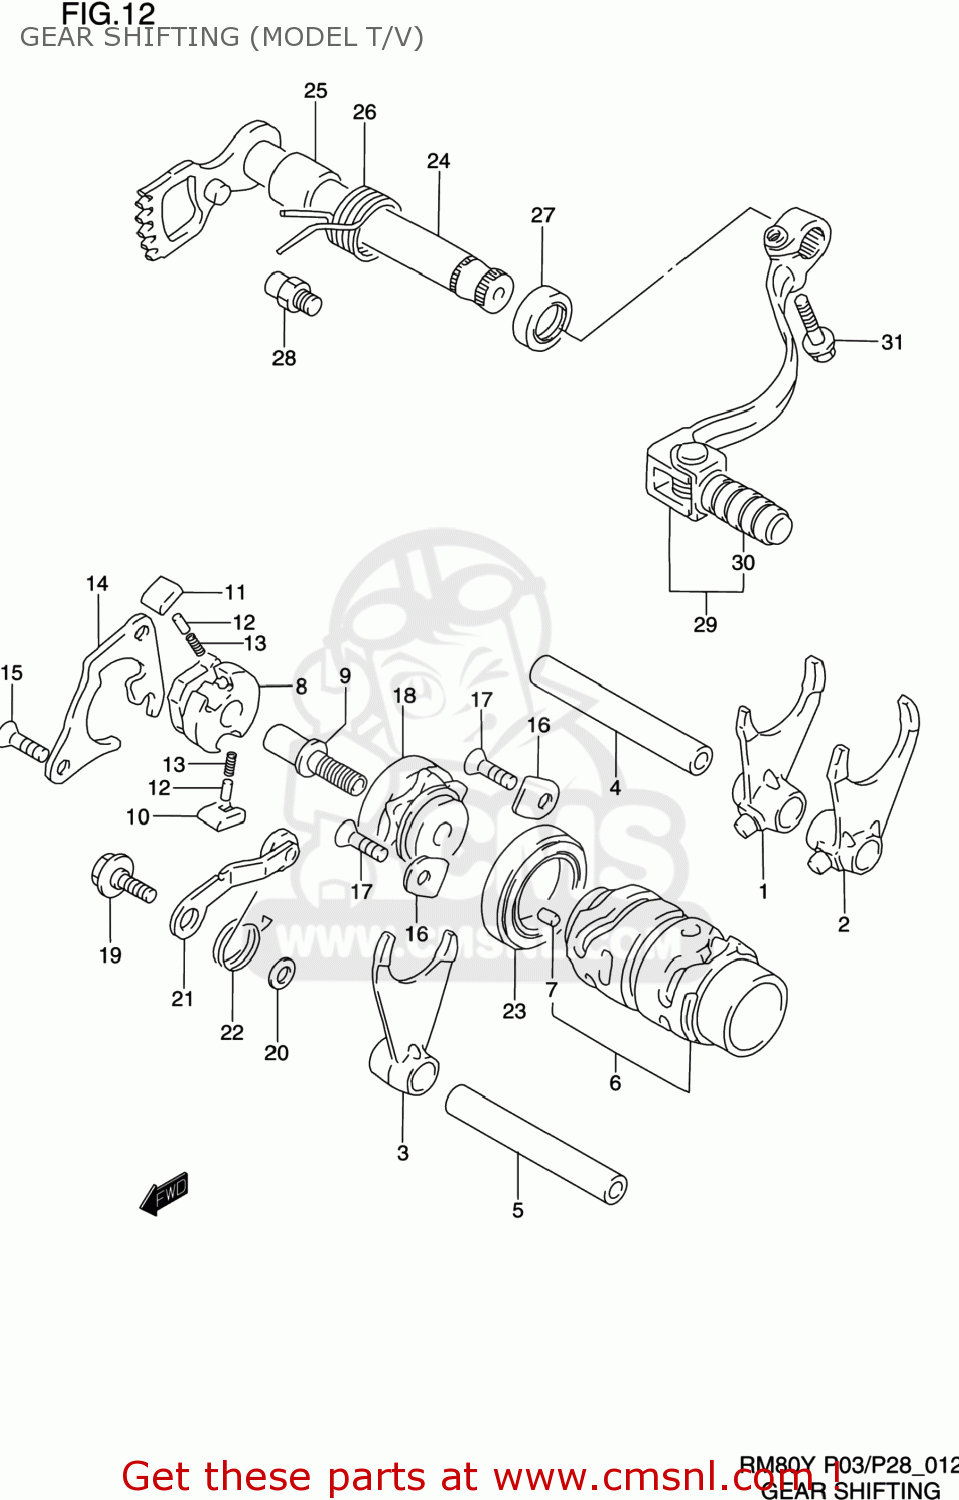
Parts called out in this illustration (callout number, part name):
1	FORK,GEAR SHIFT NO.1
2	FORK,GEAR SHIFT NO.2
3	FORK,GEAR SHIFT NO.3
4	SHAFT,GEAR SHIFT FORK
5	SHAFT,GEAR SHIFT FORK
6	CAM,GEAR SHIFT
7	PIN
8	GEAR,GEARSHIFT CAM DRIVE
9	PIN,SHIFT CAM DRIVEN GEAR
10	PAWL,GEAR SHIFT NO.1
11	PAWL,GEAR SHIFT NO.2
12	PIN(5X8)
13	SPRING
14	LIFTER,GEAR SHIFT POLE
15	SPACER(6.2X12X18)
16	SCREW
17	SCREW
18	RETAINER
19	SCREW
20	PLATE,SHIFT CAM STOPPER
21	BOLT(6X14.3)
22	WASHER
23	STOPPER,SHIFT CAM
24	SPRING
25	BEARING
26	BEARING(30X37X12)
27	SHAFT,GEAR SHIFT
28	SPACER(14X20X17.5)
29	SPRING
30	SEAL,OIL(14X22X6)
31	STOPPER,GEAR SHIFT CAM
32	LEVER ASSEMBLY,GEAR SHIFTING
33	RUBBER,GEAR SHIFT PEDAL
34	SCREW
